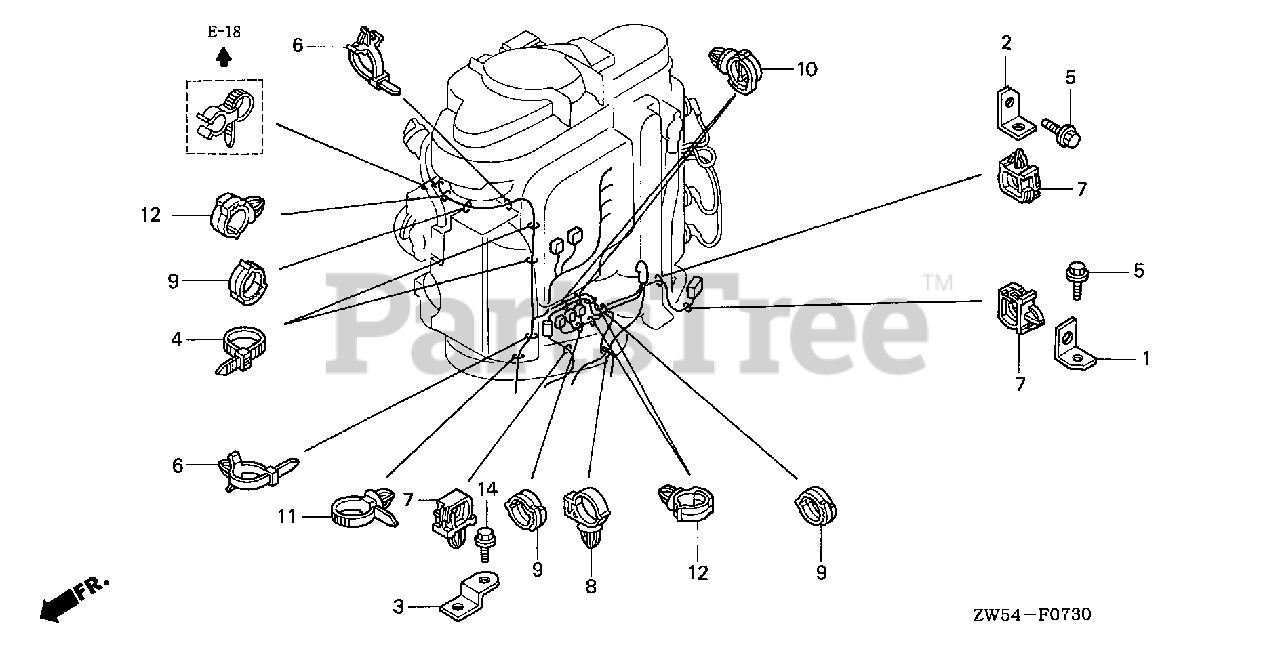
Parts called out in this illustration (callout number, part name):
1	BRACKET, CLIP (C)
2	BRACKET, CLIP (D)
3	BRACKET, CLIP (E)
4	BAND (BLACK 3.5X140)
5	BOLT, FLANGE (6X12)
6	BAND, WIRE HARNESS (150MM) (NATURAL)
7	CLIP, WIRE HARNESS (10MM)
8	CLAMP, HARNESS
9	CLIP, WIRE HARNESS
10	CLIP, HARNESS
11	BAND, WIRE HARNESS (123.5MM) (BLUE)
12	CLIP, WIRE HARNESS (BLACK)
14	BOLT, FLANGE (6X14)
